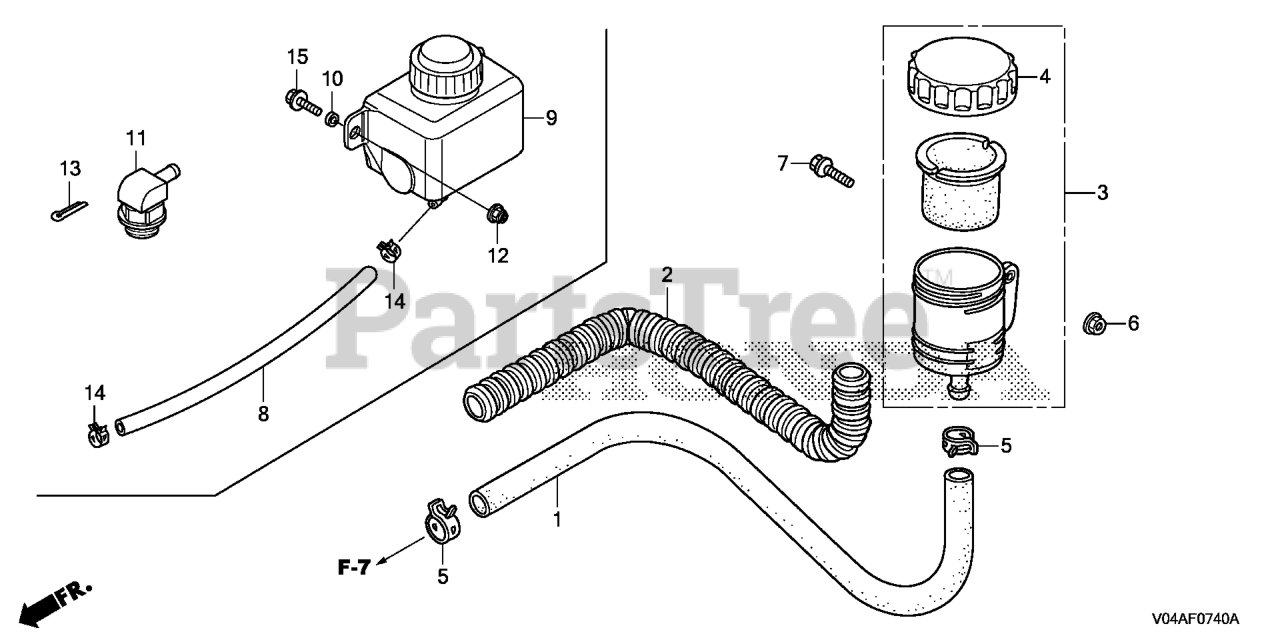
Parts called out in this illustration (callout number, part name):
8	TUBE, OIL
9	TANK, OIL
10	COLLAR, TANK
11	ELBOW ASSY., OIL
12	NUT, NYLON LOCK (6MM)
13	PIN, COTTER (3.0X18)
14	CLIP, TUBE (D8.5)
15	BOLT, FLANGE (6X16)
